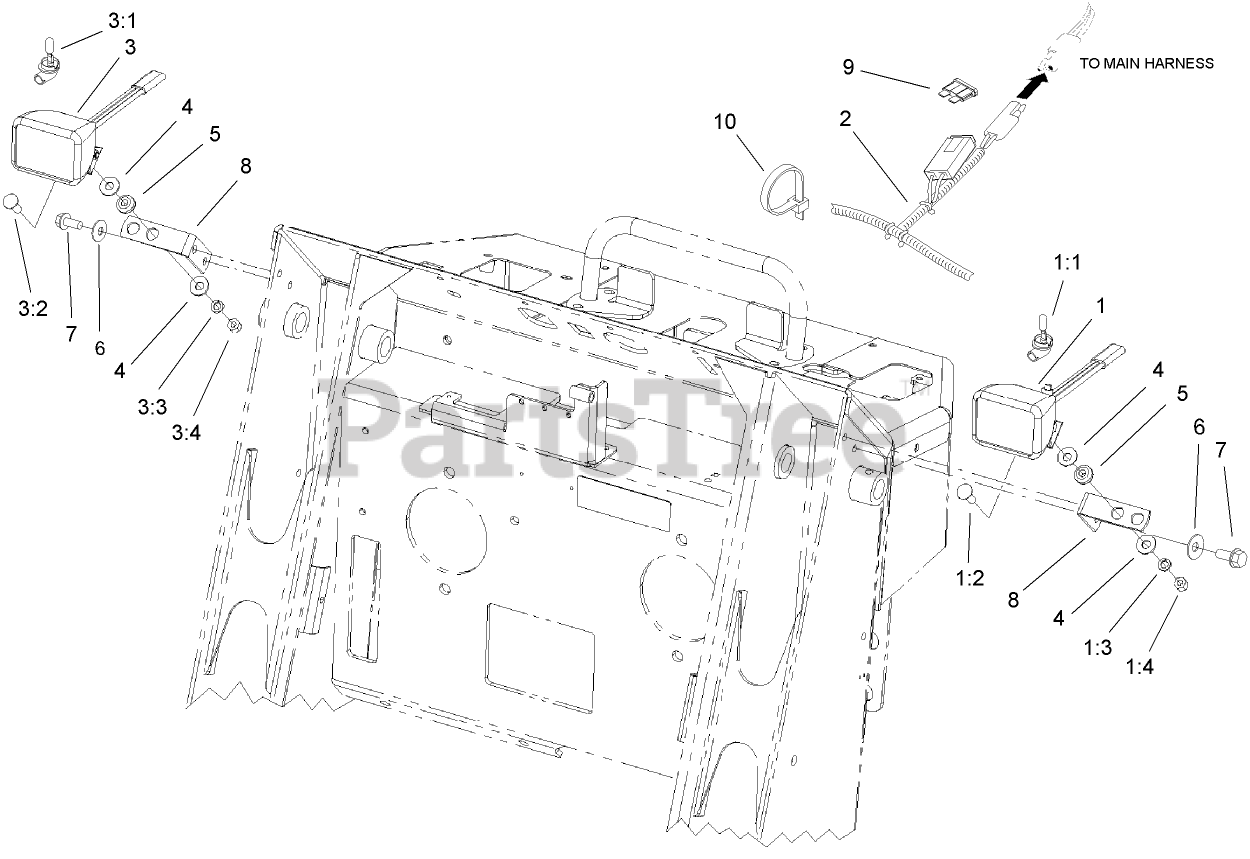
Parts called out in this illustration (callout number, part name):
1	LAMP W/SWITCH
1:1	LAMP-12 VOLT
1:2	SCREW-CARR
1:3	WASHER-LOCK
1:4	NUT-HEX
2	HARNESS-ELECTRICAL
3	LAMP ASM
3:1	LAMP-12 VOLT
3:2	SCREW-CARR
3:3	WASHER-LOCK
3:4	NUT-HEX
4	WASHER-FLAT
5	GROMMET-RUBBER
6	WASHER-BELLEVILLE
7	SCREW-HWHTF
8	Bracket-Light
9	FUSE-BLADE, 10 AMP
10	TIE-CABLE
